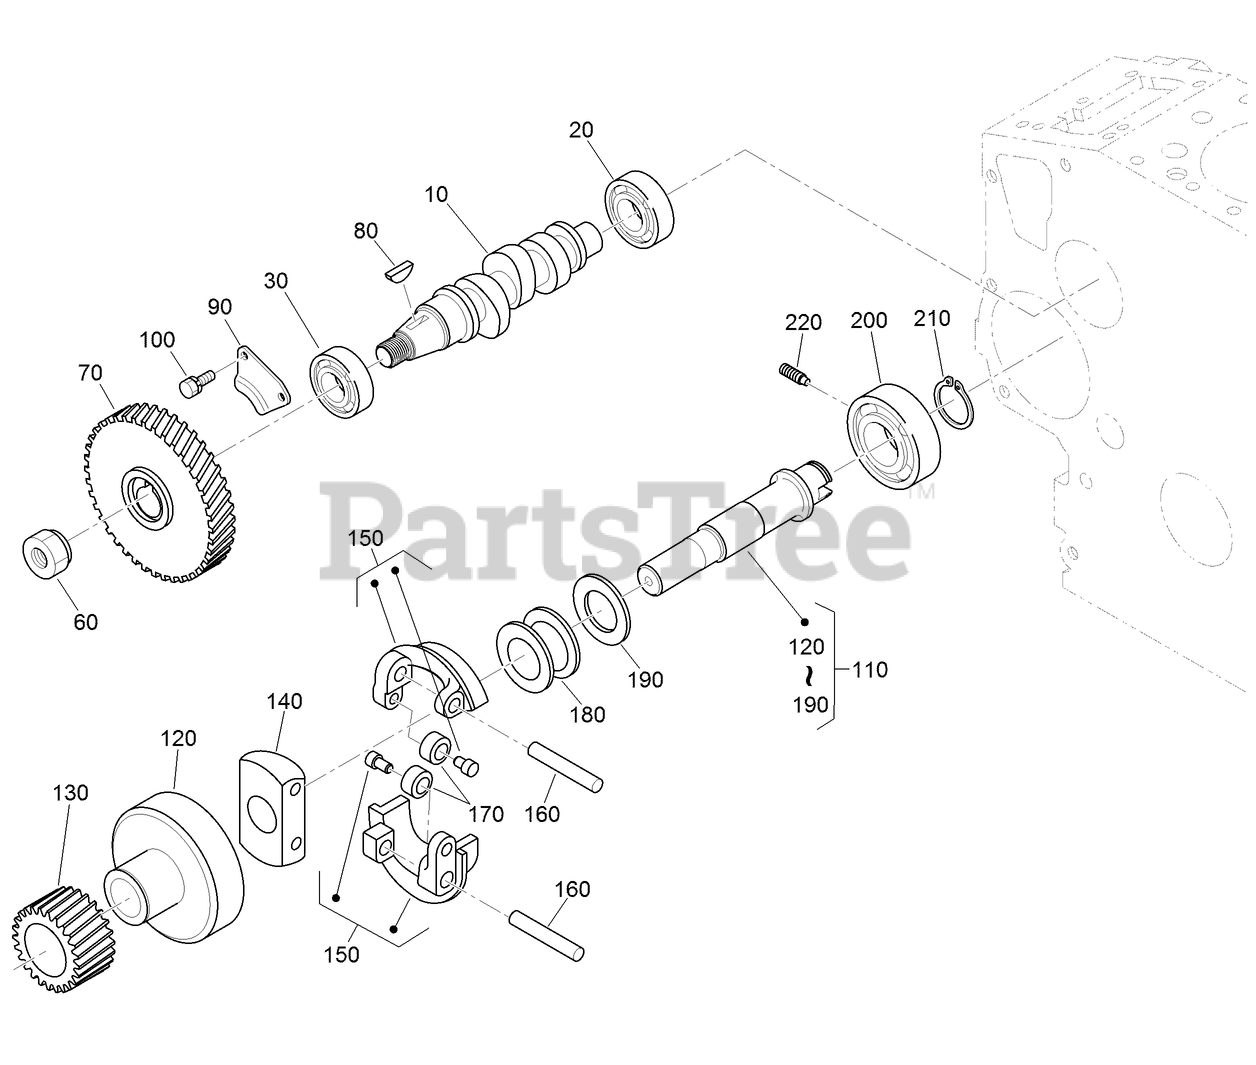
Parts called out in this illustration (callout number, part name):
10	CAMSHAFT-FUEL
20	BEARING-BALL
30	BEARING-BALL
70	GEAR-INJECTION PUMP
80	KEY-WOODRUFF
90	STOPPER-FUEL, CAMSHAFT
110	GOVERNOR SHAFT ASM
120	HOLDER-GEAR, GOVERNOR
130	GEAR-GOVERNOR
140	HOLDER-WEIGHT, GOVERNOR
150	GOVERNOR WEIGHT ASM
160	SHAFT-WEIGHT, GOVERNOR
170	ROLLER
180	SLEEVE-GOVERNOR
190	WASHER-THRUST
200	BEARING-BALL
210	CIRCLIP-SHAFT, GOVERNOR
220	SCREW-SET
